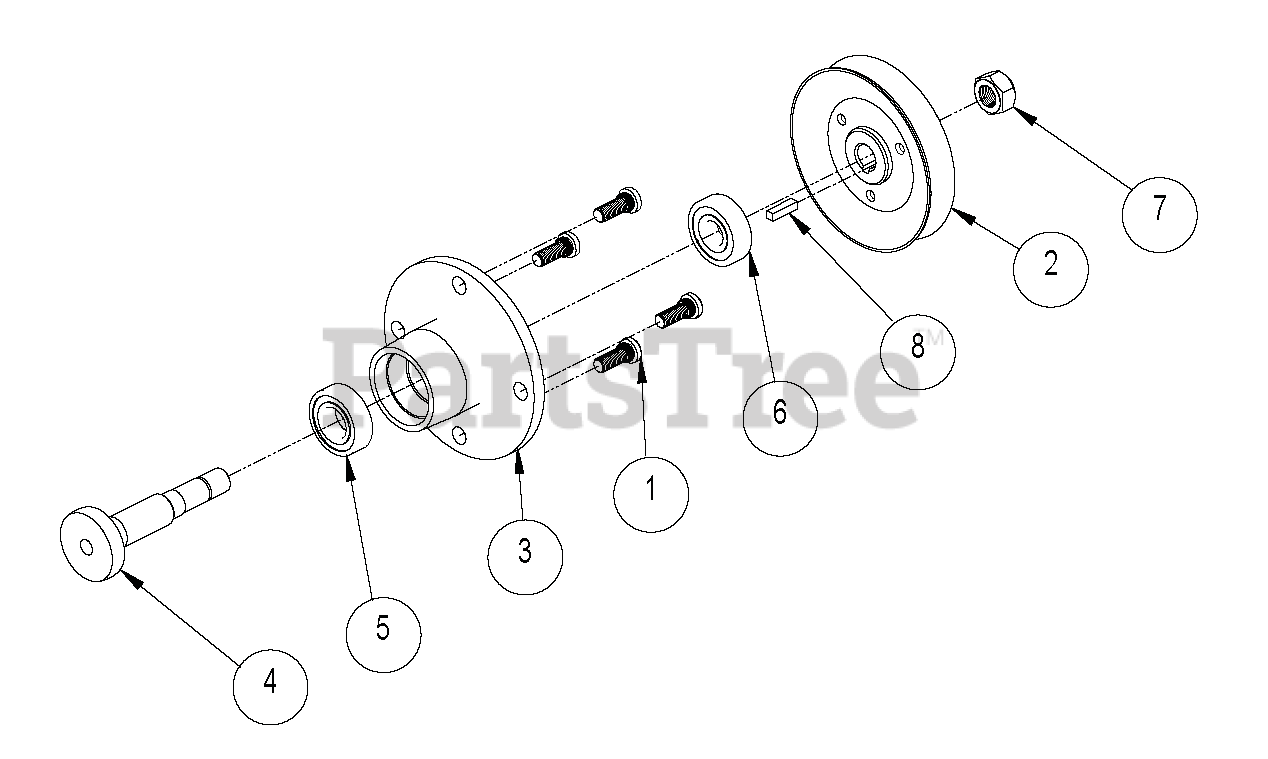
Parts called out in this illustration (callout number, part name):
1	BOLT, 7/16-20X1.22 SPC 5 Y
2	PULLEY, V-BELT 5.75X.750 W/KEY
3	SPINDLE, MACHINED BALL BRG
4	SHAFT, BLADE SPINDLE
5	BRG, BAL .984X2.05X.591 - 6205
6	BRG, BAL .787X2.05X.591
8	KEY, .250 X .250 X 1.00 SQ
